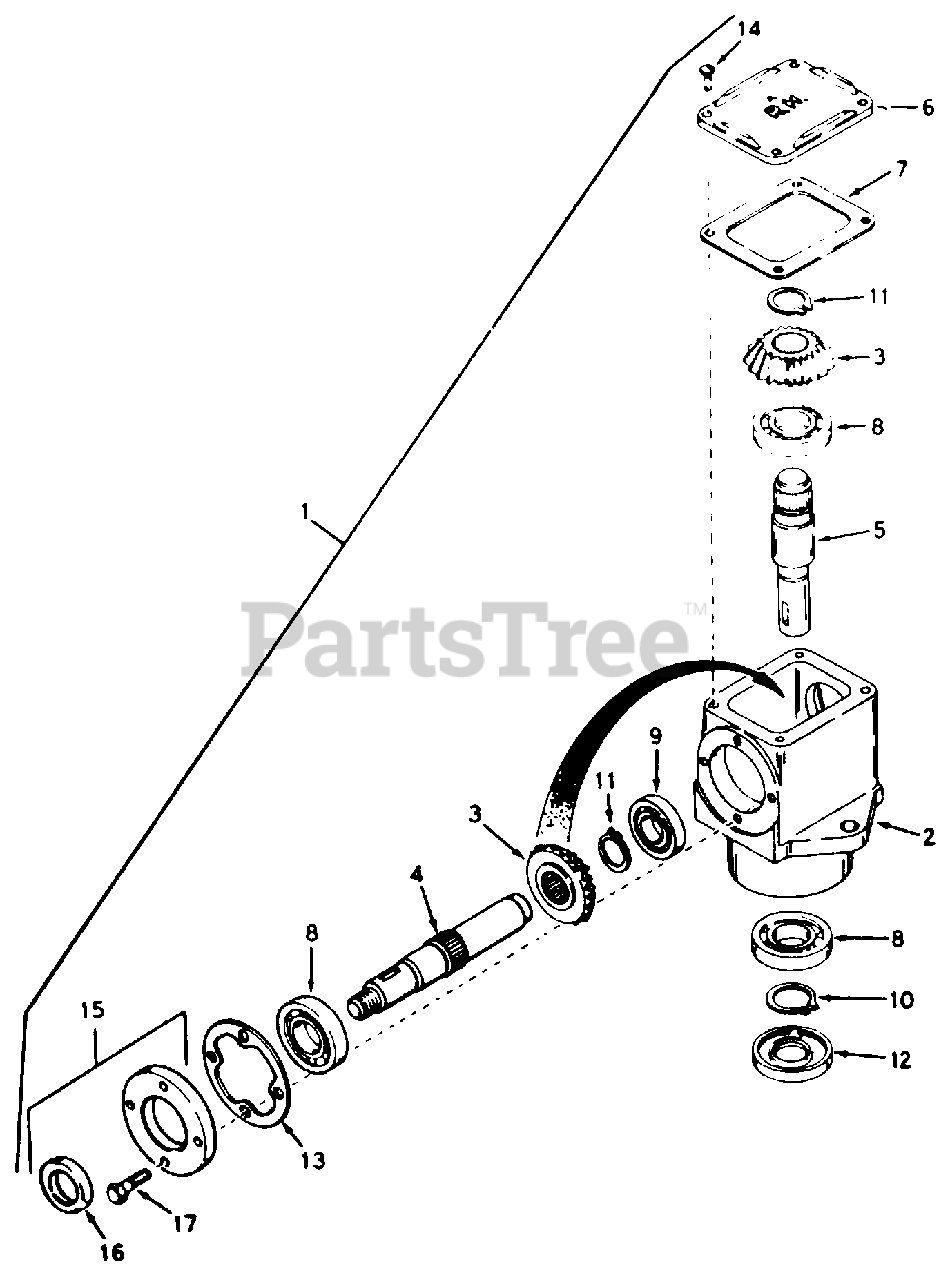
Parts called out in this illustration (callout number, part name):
1	Head Ass'y. R.H.
2	Housing: RightAngleDrive
3	Gear: Miter
4	Shaft: Input
5	Shaft: Output
6	Cover: Right Hand
7	Gasket: Cover
8	Bearing: Ball
9	Bearing: Ball
10	Ring: Snap
11	Ring: Snap
12	Seal: Oil
13	Gasket: Cap
14	Screw: Rd. Hd. Self Tap.: 10-24 x 1/2
15	Cap & Seal Ass'y.: Retainer
16	Seal: Oil
17	Screw: Hex Hd. 1/4-20 x 7/8
